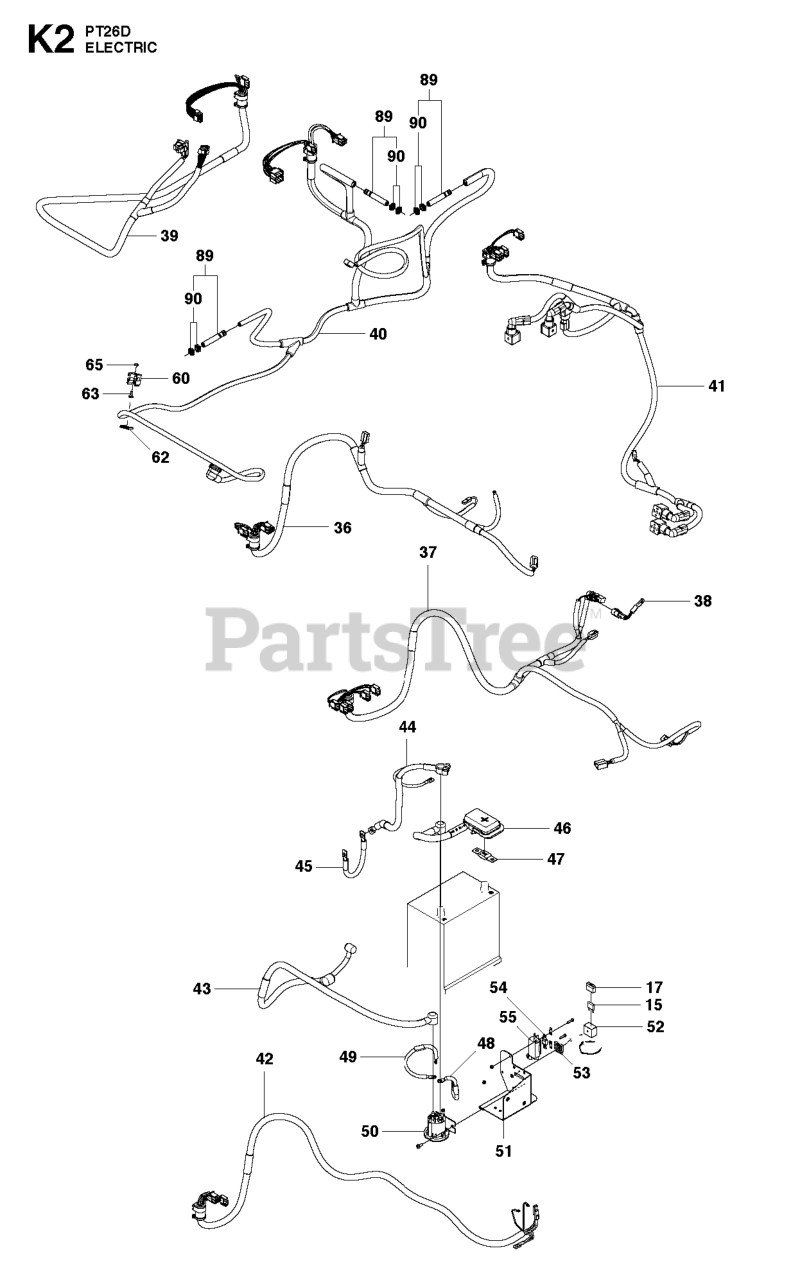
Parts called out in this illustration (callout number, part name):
17	COVER FUSE HOLDER
49	WIRING FUSE POWER
55	FUSE HOLDER
65	LOCKNUT M5
